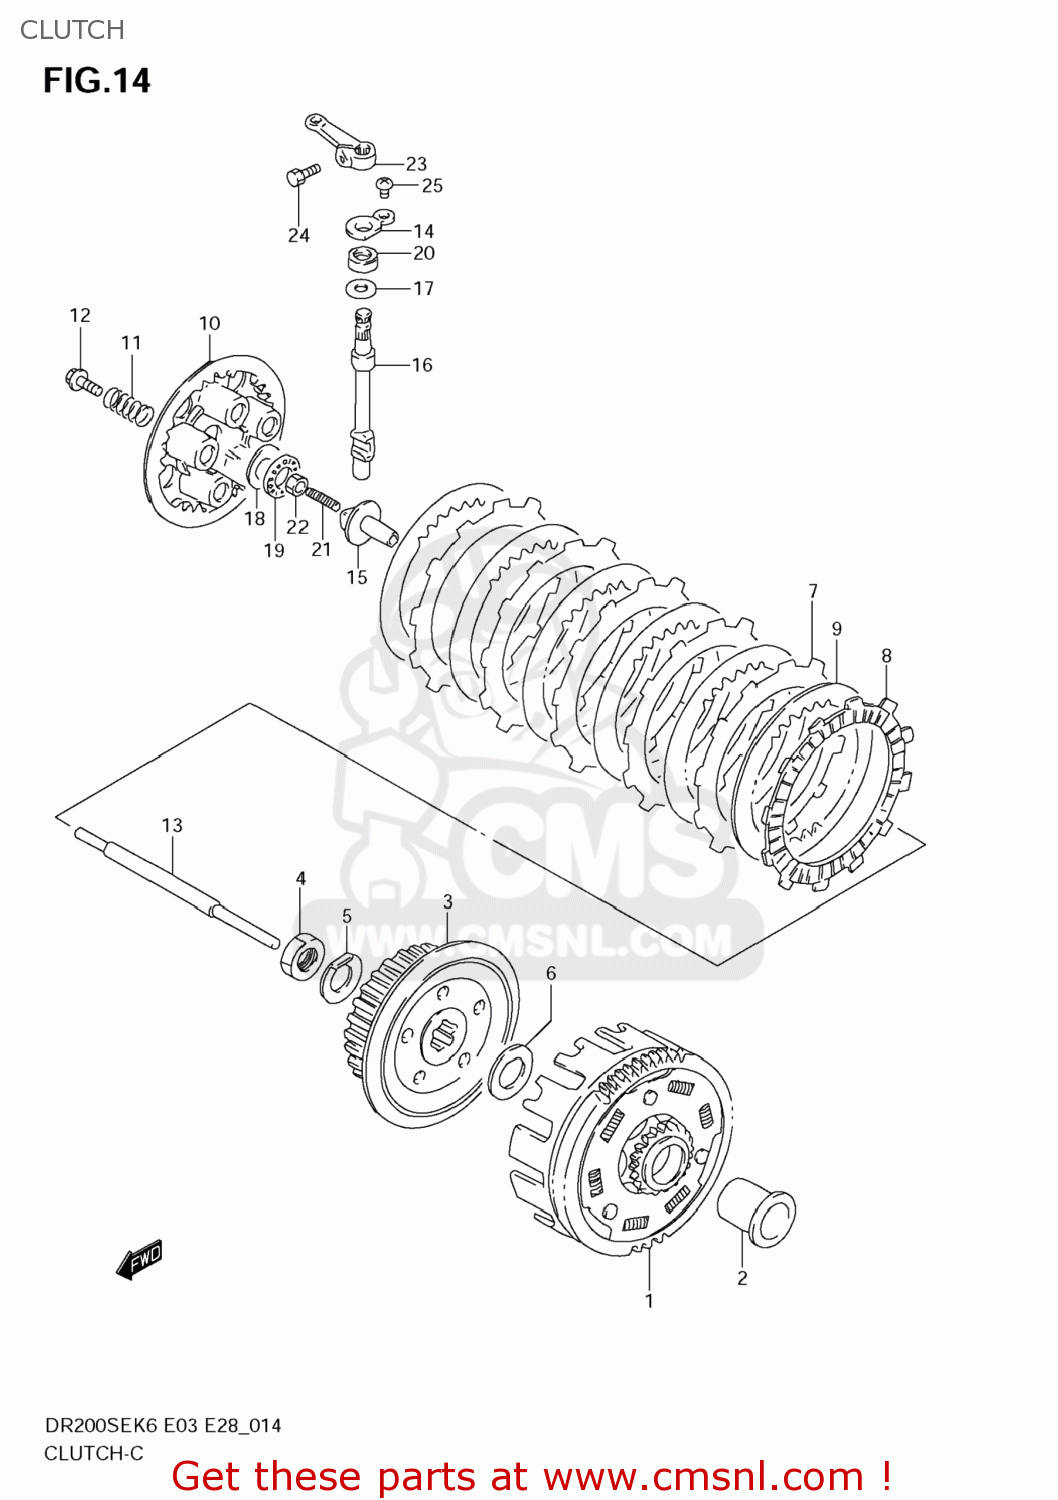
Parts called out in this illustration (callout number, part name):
1	GEAR ASSY,PRI DRIVEN
2	SPACER,PRIMARY DRIVEN GEAR
3	HUB,CLUTCH SLEEVE
4	NUT
5	WASHER
6	WASHER
7	PLATE,CLUTCH DRIVE (NAS)
8	PLATE,CLUTCH DRIVE(T:3.0) (NAS)
9	PLATE,DRIVEN(T:1.4)
10	DISC,CLUTCH PRESSURE
11	SPRING
12	BOLT(5X16)
13	ROD,CLUTCH PUSH
14	RETAINER,CL RLSE OIL SEAL
15	PIECE,CLUTCH PUSH
16	CAMSHAFT,CLUTCH RELEASE
17	SHIM(10X20X1)
18	WASHER(15.5X28X1)
19	BEARING(15X28X2)
20	SEAL,OIL(10X20X6)
21	SCREW(6X25)
22	NUT
23	ARM,CLUTCH RELEASE
24	BOLT
25	SCREW
